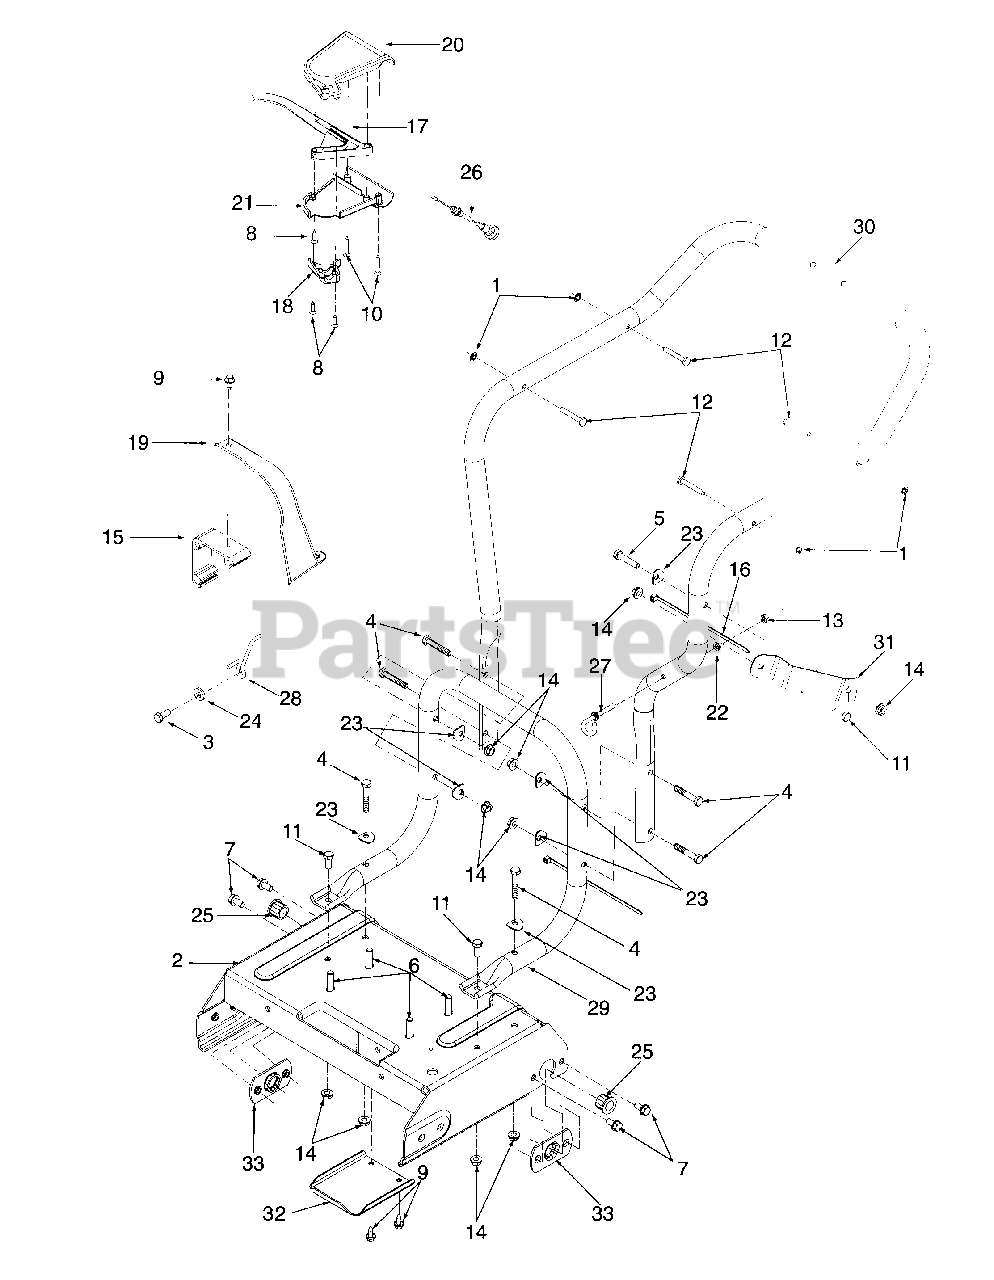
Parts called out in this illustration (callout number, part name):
1	Nut, Push, .25
2	Frame Assembly
3	Screw, Hex Cap, 5/16-24 x.75 GR5
4	Screw, Hex Cap, 5/16-18 x 1.75
5	Screw, Hex Cap, 5/16-18 x 1.5
6	Screw, Hex Wash Hd Tapp, 3/8-16 x 1.25
7	Screw, Hex Wash Hd Tapp, 5/16-18 x .62
8	Screw, Phil Cntrsnk, #10-12 x .75
9	Screw, Hex Wash Hd, 1/4-14 x .62
10	Screw, Phil Cntrsnk, #10-16 x 1.25
11	Screw, Hex Cap, 5/15-18 x.75 GR5
12	Pin, Stud, .250 x 1.75
13	Nut, Hex, 1/4-28
14	Nut, Hex Flange Lock, 5/16-18 GR5
15	Adapter, Engine Mtg
16	Cable Tie
17	Lever, Drive Control
18	Cap, Cable Mtg
19	Belt Cover
20	Upper Clutch Cover
21	Lower Clutch Cover
22	Washer, Lock, 1/4
23	Saddle Washer, .320 x .93
24	Washer, Flat, .344 x .75 x .12
25	Bearing, Flange, .631 ID x .72 OD
26	Cable, Clutch, 56.0
28	Belt Keeper
29	Handle, Lower
30	Handle, Upper
31	Bracket, Chute Stabilizing
32	Transmission Cover
33	Bracket, Axle
